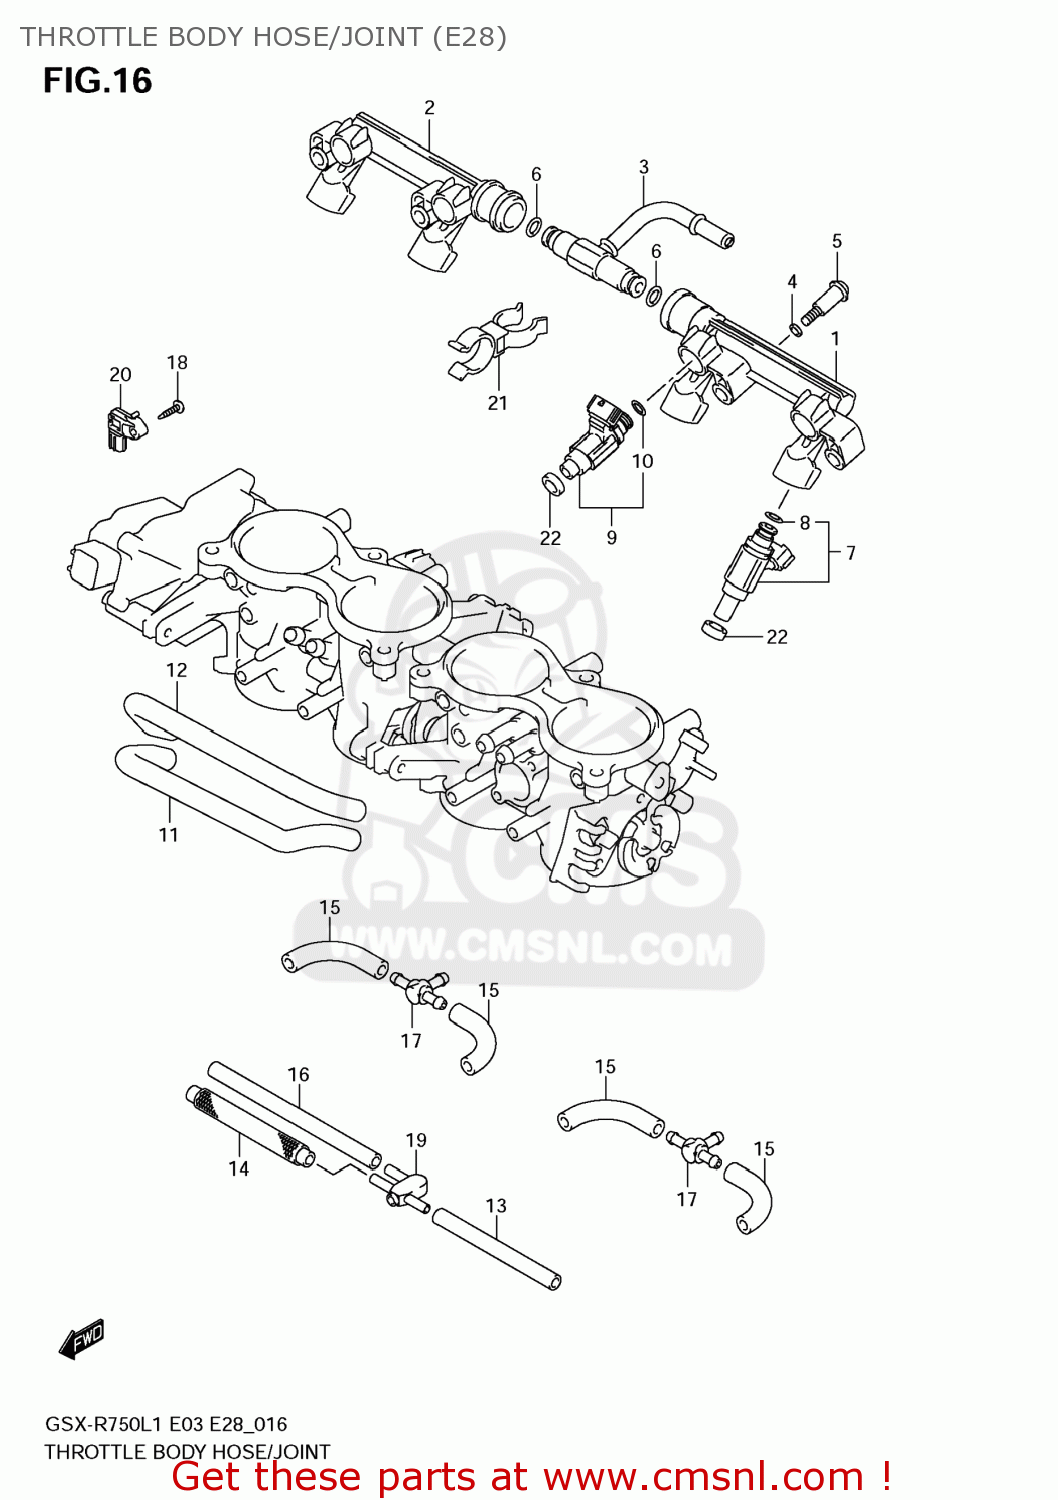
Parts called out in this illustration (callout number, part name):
1	DELIVERY PIPE
2	DELIVERY PIPE
3	NIPPLE ASSY
4	PACKING (NAS)
5	SCREW
6	O RING
7	INJECTOR ASSY
8	O-RING
9	INJECTOR ASSY
10	O-RING
11	HOSE
12	HOSE
13	HOSE
14	HOSE
15	HOSE(L:425)
16	HOSE
17	3WAY,VACUUM HOSE
18	SCREW
19	JOINT
20	SENSOR,BOOST
21	CLAMP
22	SEAL
